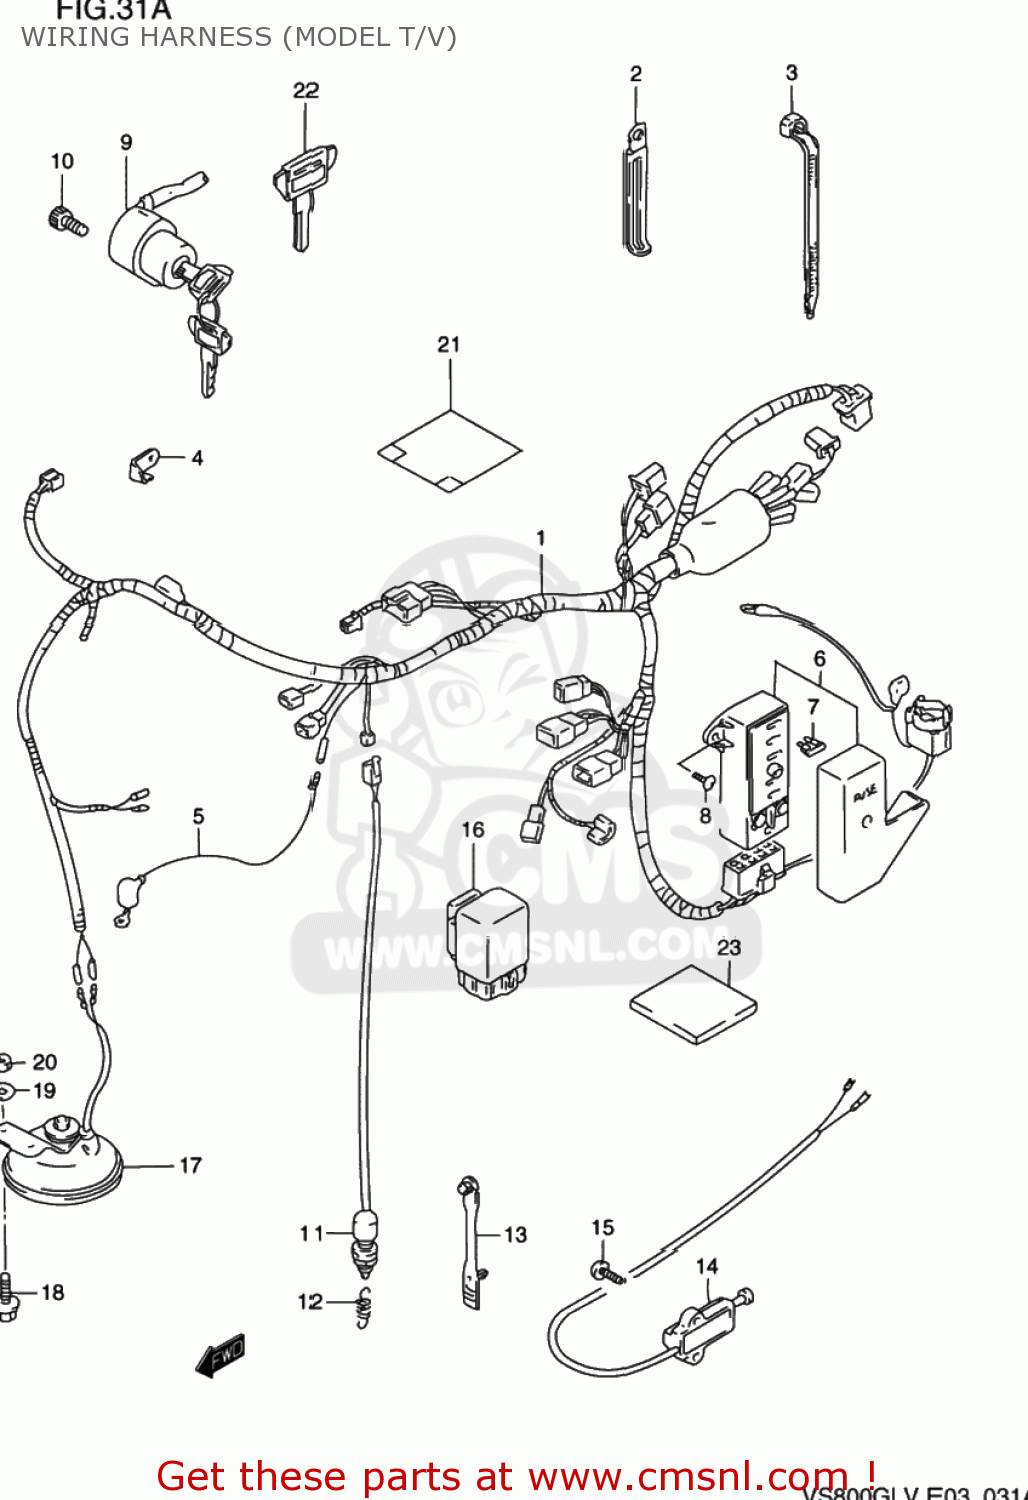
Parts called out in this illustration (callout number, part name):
1	HARNESS,WIRING
2	CLAMP(L:45)
3	CLAMP(L:95)
4	PLATE,COUPLER HOLDER
5	WIRE,WATER TEMP GAUGE LEAD
6	BOX ASSY,FUSE
7	FUSE(10A)
8	SCREW
9	SWITCH ASSEMBLY,IGNITION
10	BOLT
11	SWITCH ASSY,STOP LAMP
12	SPRING
13	CLAMP,L:88
14	SWITCH ASSY,SIDE STAND
15	SCREW
16	RELAY ASSY
17	HORN ASSY
18	BOLT
19	WASHER
20	NUT 6MM
21	COVER,WIRING HARNESS
22	KEY,BLANK(TYPE:C)
23	COVER,HARNESS
